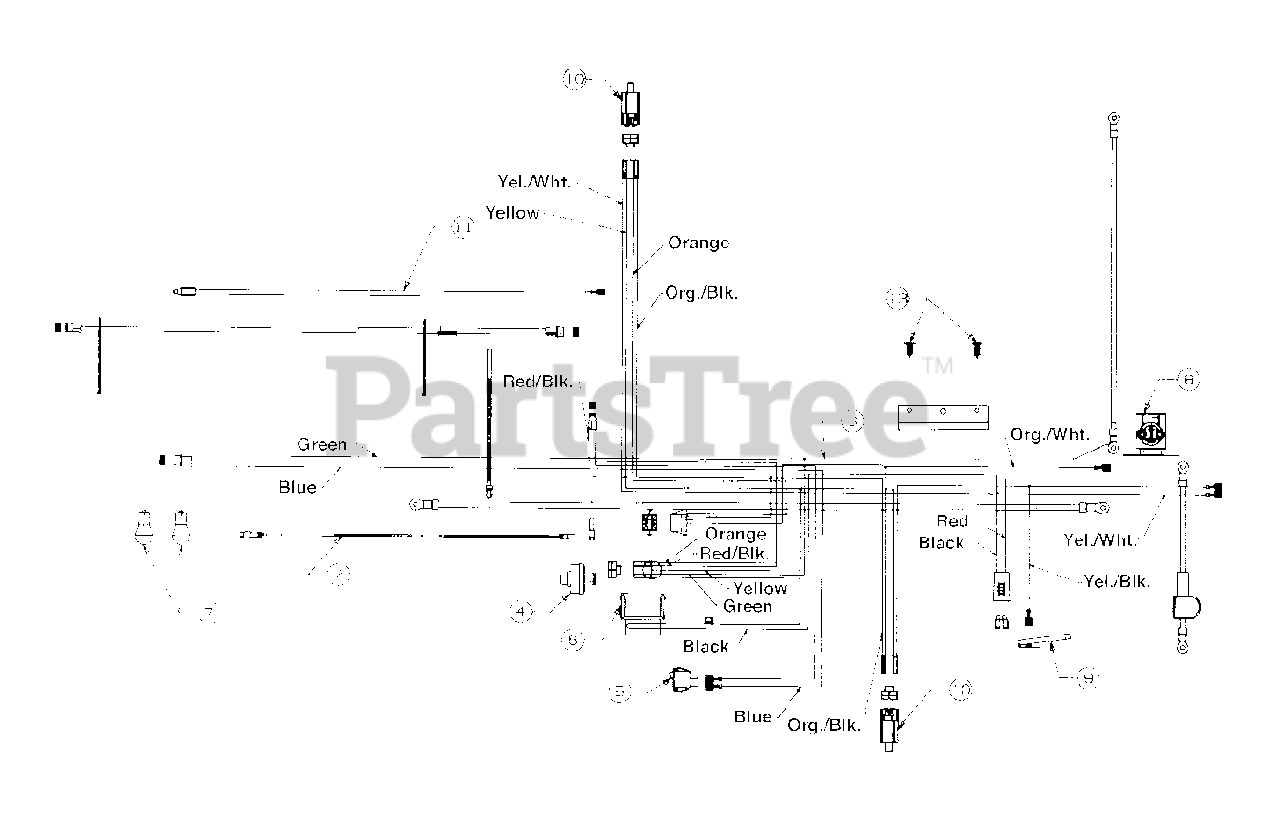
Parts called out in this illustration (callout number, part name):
2	Harness Adapter
3	Wire Harness w/Light Switch & Amp
4	Ignition Switch
5	Light Switch
6	Ammeter
7	Bulb
8	Solenoid
9	Safety Switch (Reverse)
10	Safety Switch
11	Harness Adapter (Alt.)
13	Ratchet
